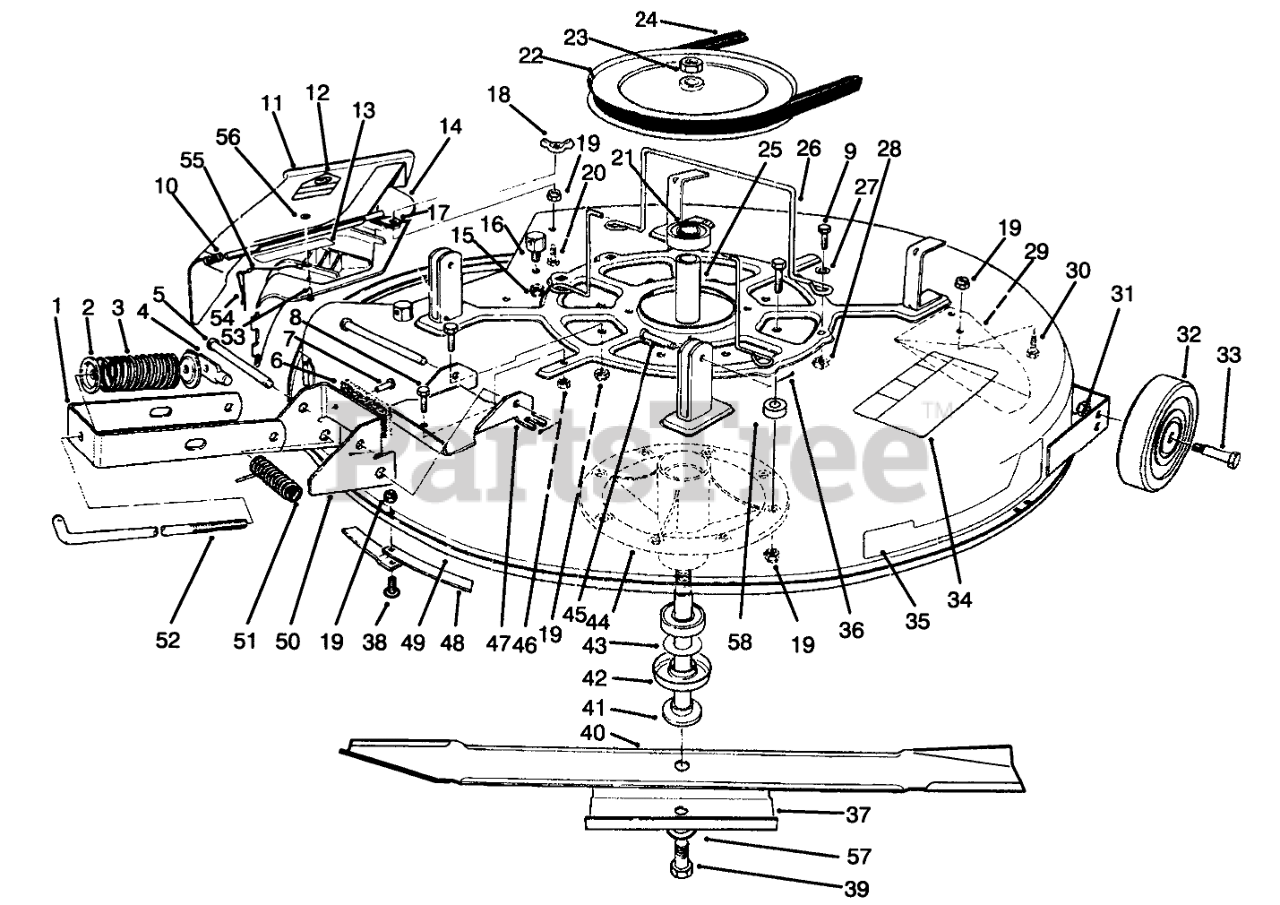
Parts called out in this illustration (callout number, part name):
1	Bracket-Engagement
2	RETAINER-SPR. TOP
3	SPRING-COMPRESSION
4	SHAFT-DECK ADJ.
5	PIN-CLEVIS
6	PAD-BRAKE
7	RIVET-BLIND
8	SCREW-HH
9	SCREW-HH
10	SPRING
11	Assembly-Deflector (Incl. Ref. #12)
12	DECAL-DANGER
13	DECAL-DANGER, DEFLECTOR
14	Assy.-Cover, Discharge (Incl. Ref. #53-56)
15	NUT-LOCK, NI
16	POST-PIVOT
17	Brace-Cover, Rear
18	NUT-WING
19	NUT-LOCK, NI
20	SCREW-HH
21	BEARING-BALL
22	PULLEY
23	NUT-HEX
24	V-BELT, DECK
25	SPACER-BEARING
26	GUIDE-BELT
27	WASHER-PLAIN
28	NUT-RETAINER
29	Kicker
30	SCREW-HH
31	NUT-LOCK, NI
32	WHEEL-DECK
33	BOLT-WHEEL
34	DECAL-DANGER, THROWN OBJECT
35	DECAL-RECYCLER
36	PIN-COTTER
37	STIFFENER
38	SCREW-PPH
39	SCREW-HH
40	Blade
41	SHAFT-SPINDLE
42	SHIELD-BEARING
43	SPACER-HARDNED
44	SPINDLE
45	PIN-CLEVIS
46	NUT-HEX
47	Plate-Deck, Brake Mtg.
48	RING-DECK
49	Deck-Cutting
50	Assembly-Brake (Incl. Ref. #6-7)
51	SPRING
52	ROD-ENGAGEMENT
53	RIVET-BLIND
54	PIN-LOCKING, CHUTE
55	LANYARD
56	WASHER-PLAIN
57	WASHER-BELLEVILLE
58	ISOLATER-SEAT
